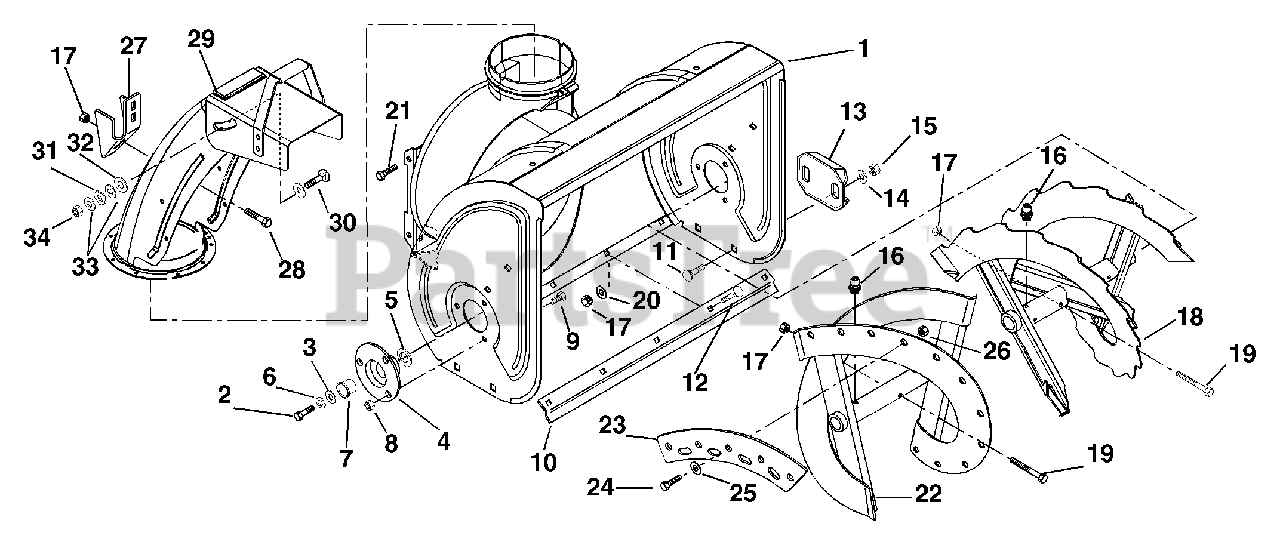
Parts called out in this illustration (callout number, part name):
1	HOUSING, BLOWER - 20"
1	HOUSING, BLOWER - 24"
2	@BLT-HEX .31-18X.50 GR5 YWZC
3	WSHR-FL-STL .347X1.254X.048YWZ
4	BEARING FLANGE ASSEMBLY
5	@WSHR-FL-STL.812X1.50X.135YWZC
6	@WSHR-LK .31X.078 REG YWZC
7	BSHG-FLG .750X1.000X.625X1.250
8	WSHR-FL-STL .125X.312X.032
9	BLT-SERNK SL .25-20X.50 YWZC
10	SCRAPER BLADE
11	BLT-RHHDSQSHNK .38-16X.75 G2YZ
12	BLT-RDHDSQSHNK.25-20X.50 YWZC
12	@BLT-RDHDSQNK .25-20X.50 G5YZ
13	SKID SHOE, REVERSIBLE - ORANGE
14	@WSHR-FL-STL.38X.875X.083 YWZC
15	@NUT-LK-CTR .38-16 YWZC
16	ZERK,FITTING .25X.125 DRIVE IN
17	@NUT-LK-CTR .25-20 YWZC
18	RAKE, RIGHT-24"(.75ID X 10.88)
18	RAKE, LEFT-24(.75ID X 10.88OD)
19	SHEAR BOLT WITH NUT
20	@WSHR-FL-STL.281X.62X.065 YWZC
21	@SCR-TAP .38-16X.75 HWH TR YWZ
22	RAKE, RIGHT-20(.75ID X 10.5OD)
22	RAKE, LEFT-20"(.75ID X 10.5OD)
23	RAKE EDGE W/HARDWARE
24	BLT-HEX 10-24X.63 PL
25	@WSHR-FL-STL .188X.438X.049 YZ
26	NUT-LK TOP 10-24 PL
27	CHUTE STRAP
28	@BLT-HEX .25-20X.50 GR5 YWZC
29	CHUTE, DISCHARGE W/CAP & DECAL
30	@BLT-RHDSSQNK .31-18X.75 G5YZ
31	WAVE WASHER .390X.655X.110
32	WSHR-PLASTIC .390X.875X.062
33	@WSHR-FL-STL.344X.688X.065YWZC
34	@NUT-LK-CTR .31-18 YWZC
